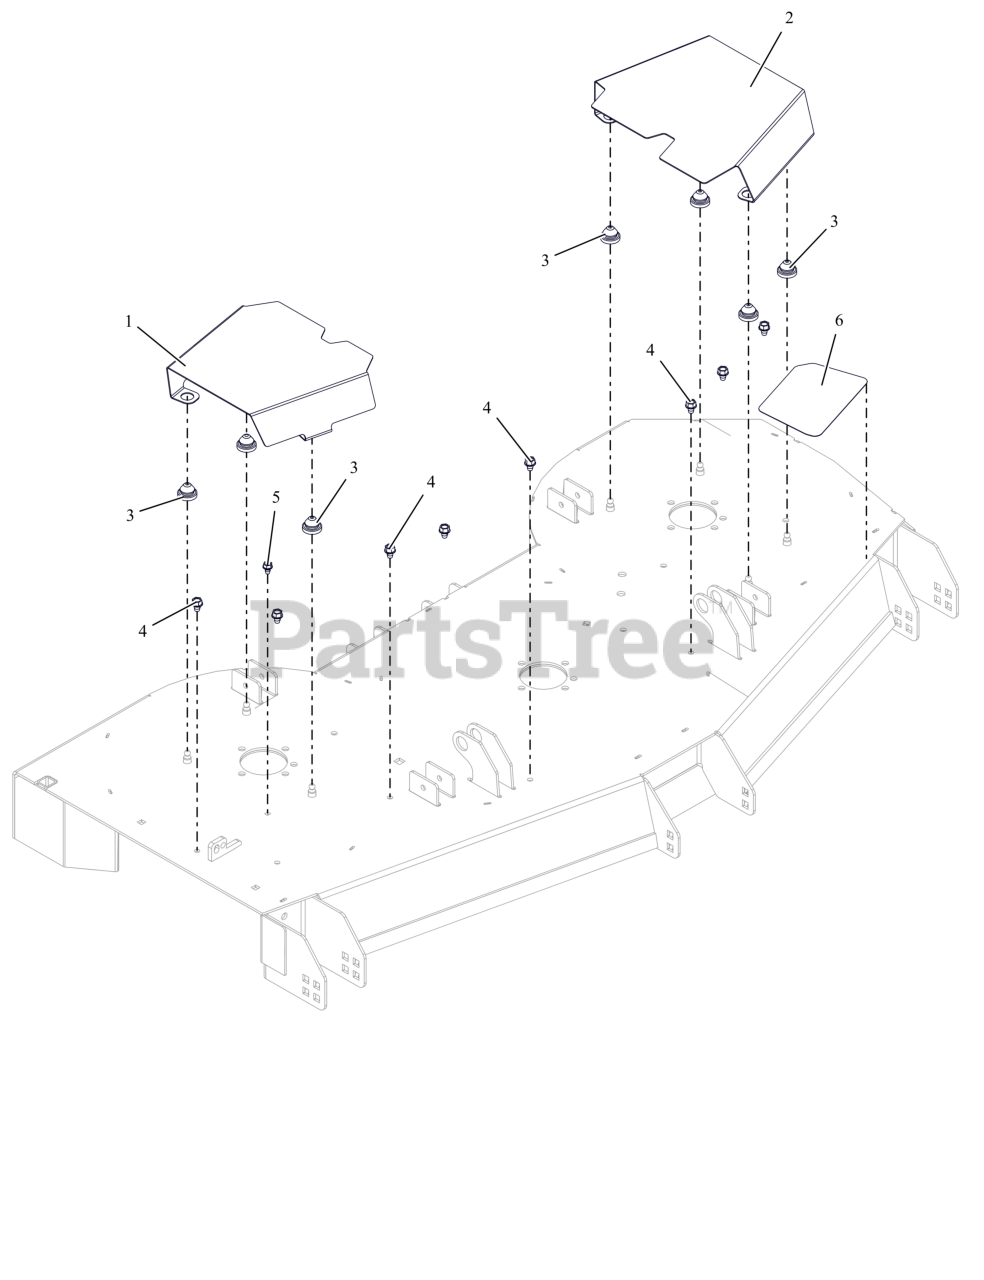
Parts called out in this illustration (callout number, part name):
1	COVER- BELT 60" RIGHT
2	COVER- BELT 60" LEFT
3	COUPLING, RUBBER PUSH-IN
4	SCR,TAP .375-16X.50 HWH TR ZCC
5	SCR,TAP .312-18X.50 HWH TR ZCC
6	GRIP, STEP ANTI SKID HD XF3
